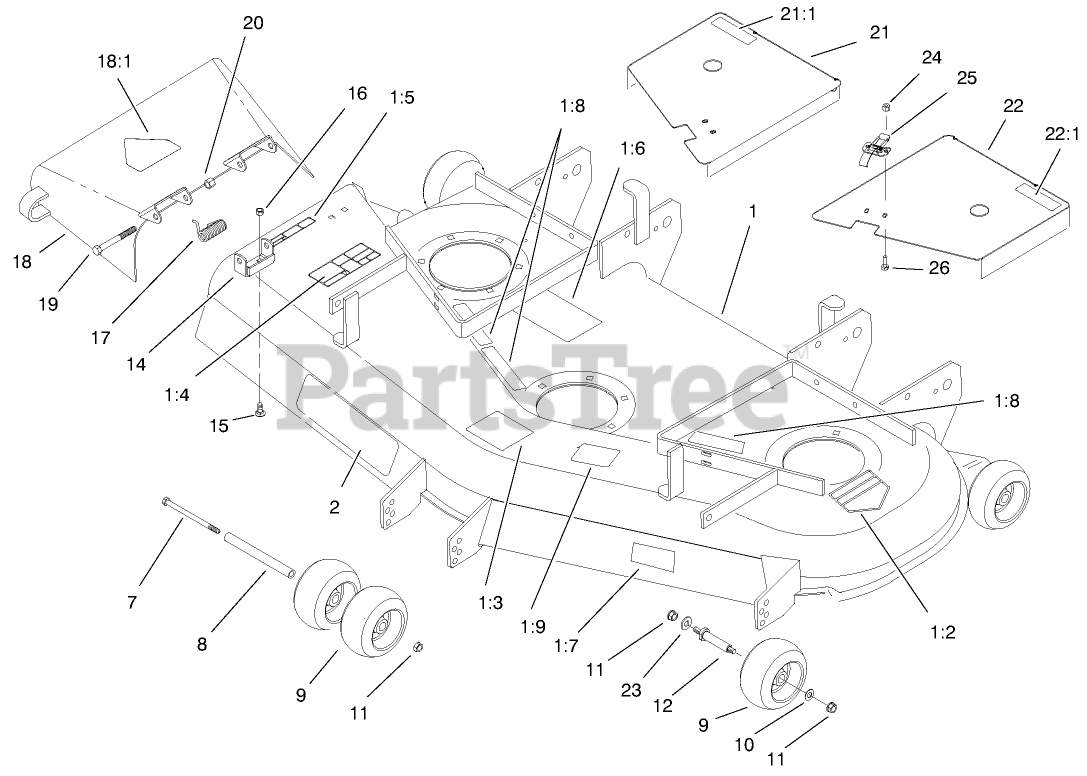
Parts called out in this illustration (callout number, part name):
1	Deck ASM
1:2	DECAL-DANGER
1:3	DECAL-WHEEL, GAGE
1:4	DECAL-DANGER, THROWN OBJECT
1:5	DECAL-DANGER
1:6	DECAL-BELT ROUTING
1:7	DECAL
1:8	DECAL-COVER, MISSING
1:9	DECAL-TORQUE, BLADE BOLT
2	DECAL
7	SCREW-HH
8	SPACER-WHEEL
9	WHEEL-GAGE
10	WASHER-FLAT
11	NUT-LOCK, NI
12	SPACER
14	BRACKET-PIVOT
15	SCREW-CARR
16	NUT-LOCK, CONE
17	SPRING
18	DEFLECTOR ASM, 52" W/DECAL
18:1	DECAL-DANGER
19	SCREW-HH
20	NUT-HEX
21	COVER ASM-RH
21:1	DECAL-DANGER
22	LH COVER ASM
22:1	DECAL-DANGER
23	WASHER-BELLEVILLE
24	NUT-LOCK, FLANGE
25	CLAMP-SLOTTED
26	SCREW-HWH
